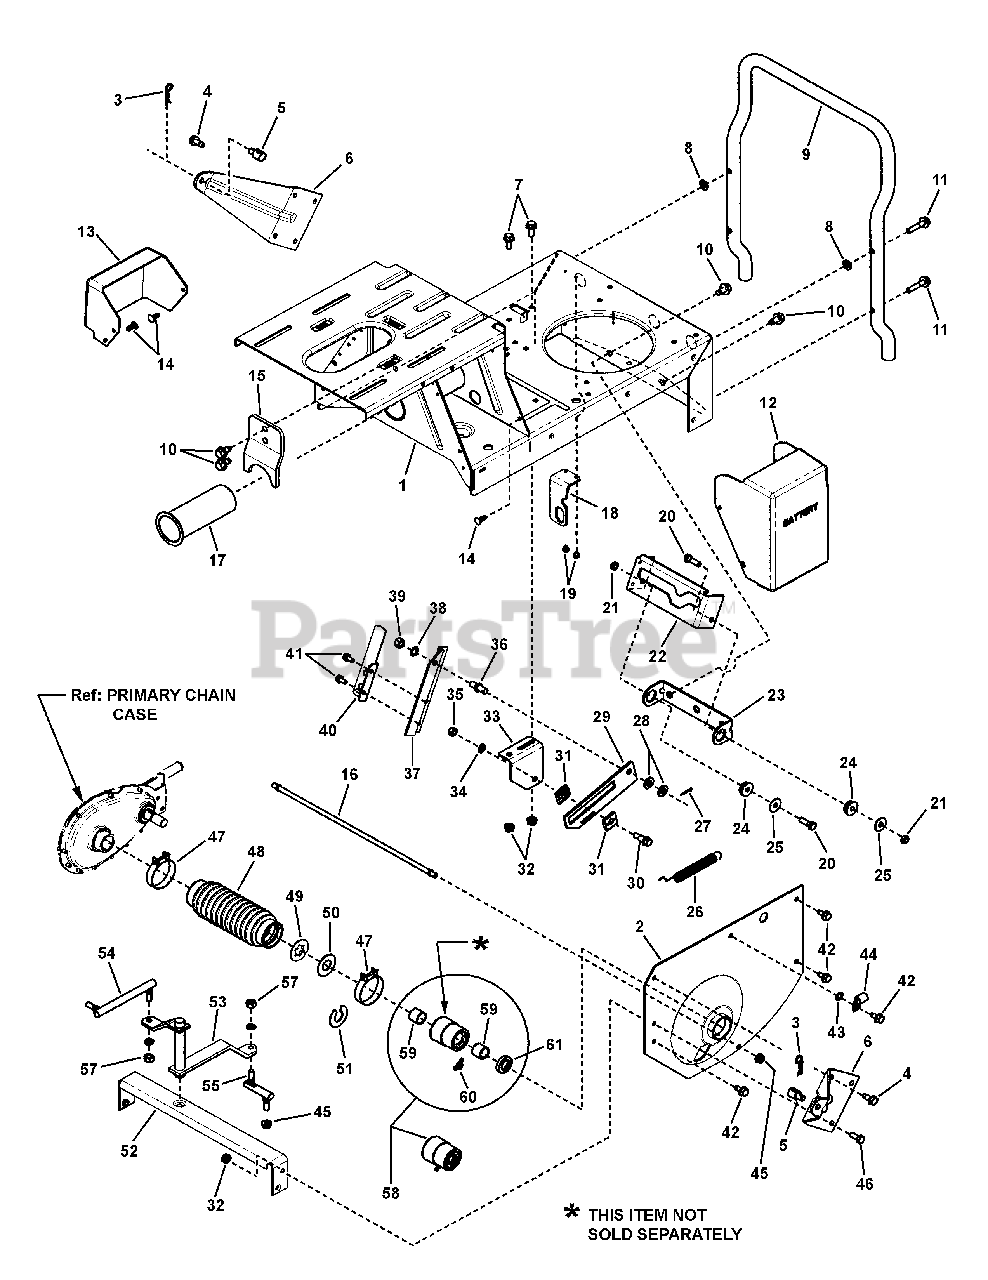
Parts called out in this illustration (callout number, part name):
1	WELDMENT, Main Case (Standard), Red
2	FENDER, 1.625 ID Hole, LH, RER
3	PIN, Hair, 3/32 x 1 5/8
4	SCREW, 5/16-18 x 3/4" Hex Washer Self-Tap
5	SWIVEL, Adjustable, 5/16-18+.109 hole
6	WING, Rear, Red
7	SCREW, Flange, Whiz-Lock, 5/16-18 X 3/4
8	WASHER, 5/16, Flat SAE, Zinc/Clear
9	BUMPER, Rear, Black
10	SCREW, 3/8-16 x 5/8" Hex Washer Self-Tap, BP
11	SCREW, Hex Washer Self-Tap, 5/16-18 x 1-1/2
12	COVER, Battery
13	COVER, Solenoid
14	FASTENER, 1/4 x 3/4 Ratchet
15	BRACKET, Belt Adjuster, Red
16	TIE ROD, (5/16-24 thread- both ends)
17	BUSHING, Pivot, 1.89X5.88X.1
18	BRACKET, Switch, Black
19	SCREW, #10-32 x 3/8, Torx Hex Washer Head Self-Tap, ZC/CL
20	SCREW, 5/16-24 x 1 Hex Head Cap, GR 5, BZ
21	NUT, 5/16-24, Hex Crown Lock,GR C, Zinc/Clear
22	YOKE
23	COLLAR, Yoke
24	BEARING, Yoke
25	WASHER, 5/16" I.D. 1" O.D. Fender
26	SPRING, Clutch / Brake
27	PIN, 3/32 X 3/4, GR5, Cotter, Zinc/Clear
28	WASHER, .406
29	SLIDE, Drive Support, Black
30	BOLT, 5/16-18 x .530 Shoulder, GR 2, Zinc/Clear
31	SLIDE HALF
32	NUT, Serrated Lock Flange, 5/16-18
33	BRACKET, Drive Support
34	WASHER, .32 X .58 X .08, Split Lock, YZ
35	NUT, 5/16-18, GRB, Zinc/Clear
36	STUD, Clutch Link (3/8-24 thread)
37	ARM, Yoke
38	WASHER, 3/8 Internal Tooth Lock, BZ
39	NUT, 3/8-24, Hex, Grade 5, YZ
40	ASSEMBLY, Leaf Spring
41	SCREW, 1/4-20X.500, Hex HD, Self-Tap, Zinc/Clear
42	SCREW, Hex Washer Head, Taptite, 5/16-18 x 5/8
43	WASHER, 5/16, Internal Lock, Zinc/Clear
44	CLIP, Wire 7/16
45	NUT, 5/16-24 Hex Flange Lock, ZP
46	SCREW, 5/16-18 x 3/4 Hex Head Cap, GR 5, YZ
47	CLAMP, 2 ID
48	BOOT, Rear Axle, Thick Flange
49	WASHER, Thrust, (Hex Flanged)
50	WASHER, Thrust, (.765 ID, 1.625 OD)(Nylon)
51	WASHER, Notched Shim, Nylon (Can make from 7011071)
52	BRACE, CROSS
53	WELDMENT, Shift Arm, Black
54	SHIFT LINK, Long (5/16-24 both ends)
55	SHIFT LINK, Short (1.44 Long, 5/16-24 thread)
57	NUT, 5/16-24, Hex, GR5, Zinc/Clear
58	ASSEMBLY, 3/4" DX Axle Bearing, (Includes 7074182, 7074500, & 7075848)
59	BEARING, 3/4" ID, DX
60	FITTING, Lube, 45 Degree, 3/16 w/Hex (long shank)
61	SEAL, .750X1.25X.25, Dust / Grease
